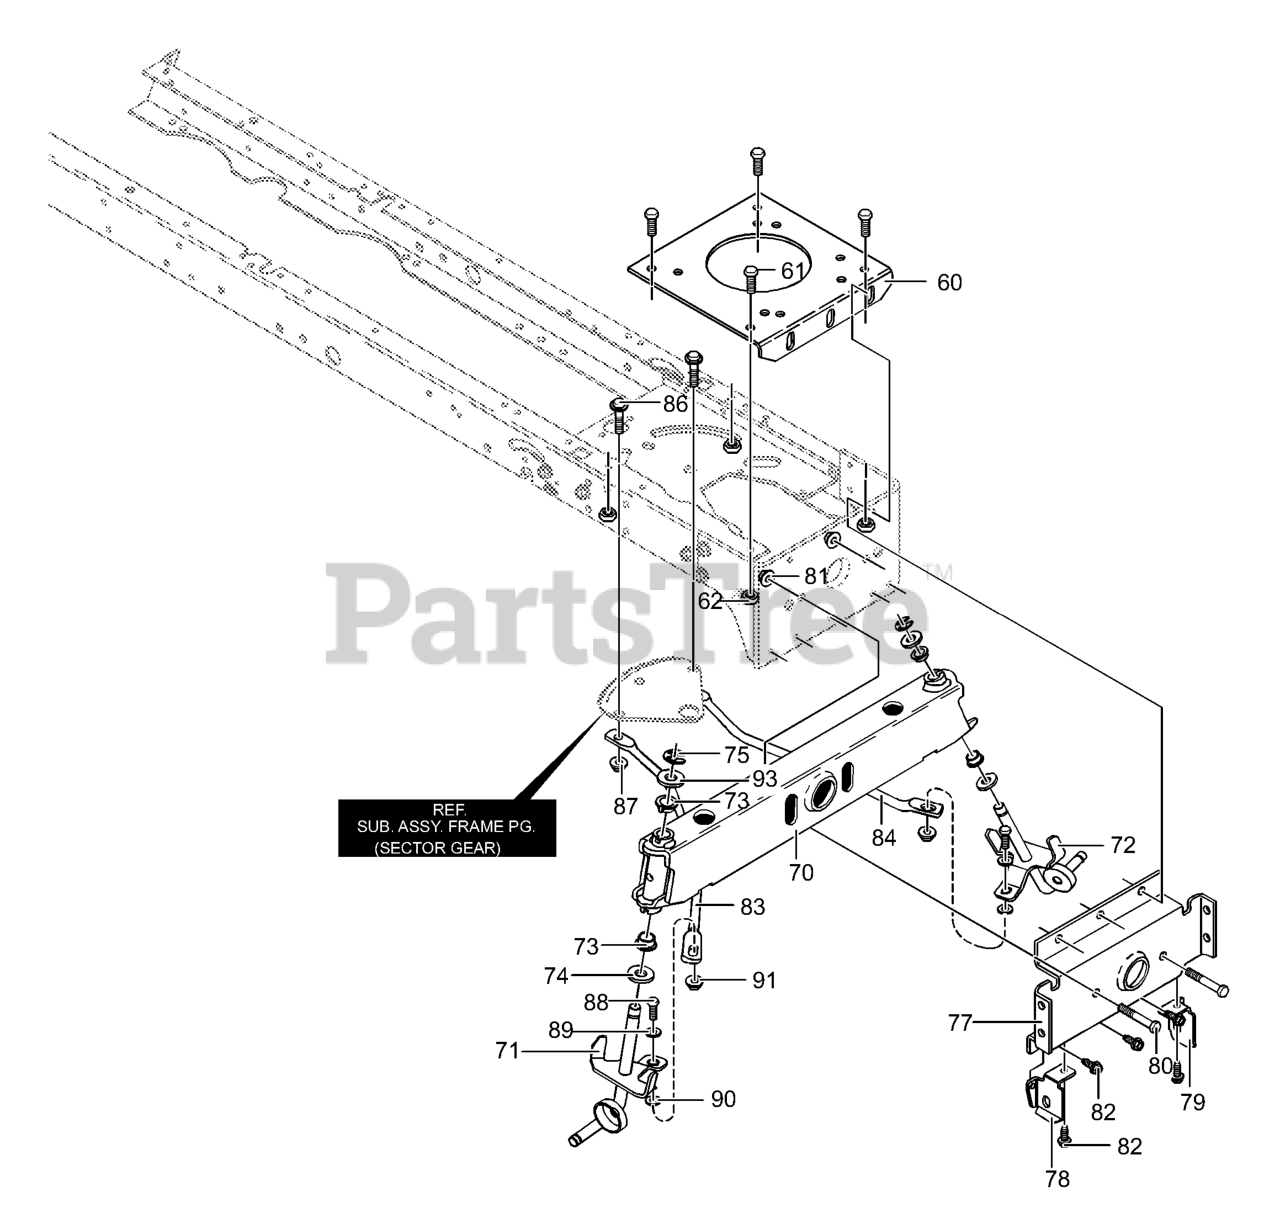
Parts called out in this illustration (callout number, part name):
60	Engine Plate
61	Screw, .312-18x.75
62	Nut, 5/16-18
70	Axle, Cast Machined
71	Spindle, RH
72	Spindle, LH
73	Bearing, Spindle
74	Washer, .766IDx1.62ID
77	Hanger, Axle
78	Hanger, Deck RH
79	Hanger, Deck LH
80	Screw, 5/16-24 x 2.75
81	Nut, .32-24 Flangelock
82	Screw, .5/16-24X2.75
83	Drag Link, RH
84	Drag Link, LH
86	Shoulder Bolt
87	Nut, 3/8-16
88	Screw, 3/8-16 x 1.50
89	Flatwasher
90	Flatwasher
91	Nut, 3/8-16
